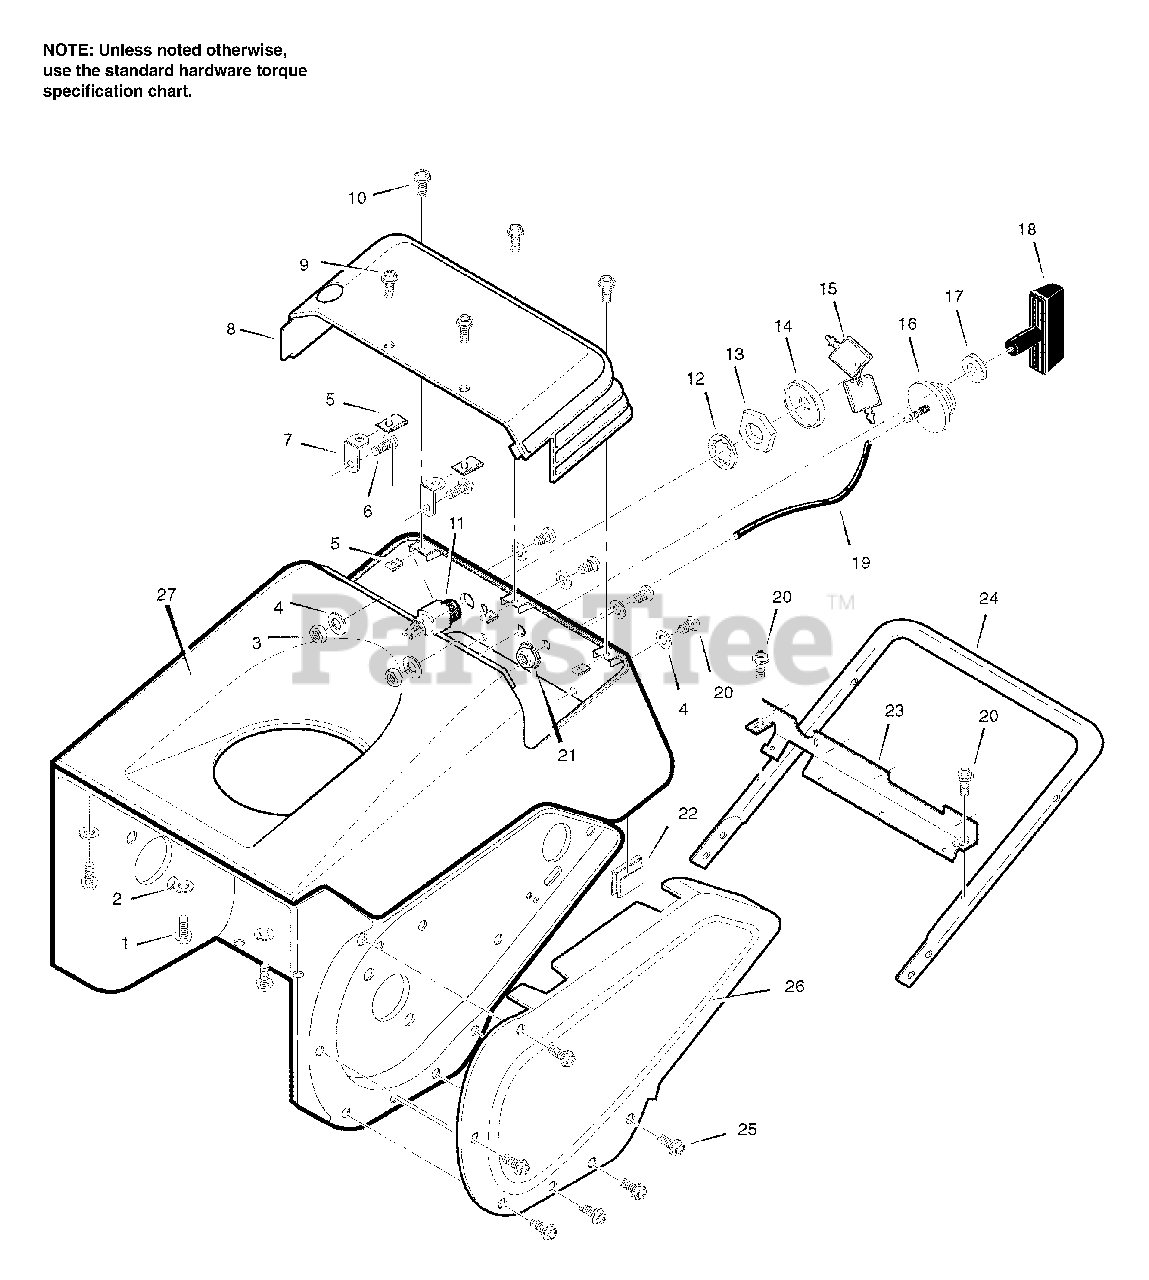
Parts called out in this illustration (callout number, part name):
1	SCREW 10-14 x .63
2	WASHER, FLAT
3	NUT, LOCK 10-24
4	WASHER, FLAT
5	NUT, U TYPE
6	SCREW 10-24 x .50
7	BRACKET, ACCESS COVER
8	COVER, ENGINE ACCESS
9	SCREW 10-16 x .62
10	SCREW 10-16 x .75
11	IGNITION SWITCH
12	WASHER, INTERNAL LOCK
13	NUT, .62-32 PLASTIC
14	BOOT, SWITCH
15	KEYS & RING
16	PRIMER BULB
17	GROMMET & WASHER
18	KNOB, STANDARD T
19	HOSE, PRIMER
20	SCREW 10-24 x .63
21	NUT .25-20 KEPS
23	BRACKET, SHROUD MTG
24	LOWER HANDLE
25	SCREW 10-24 x .38
26	COVER, BELT
27	COVER, TOP
